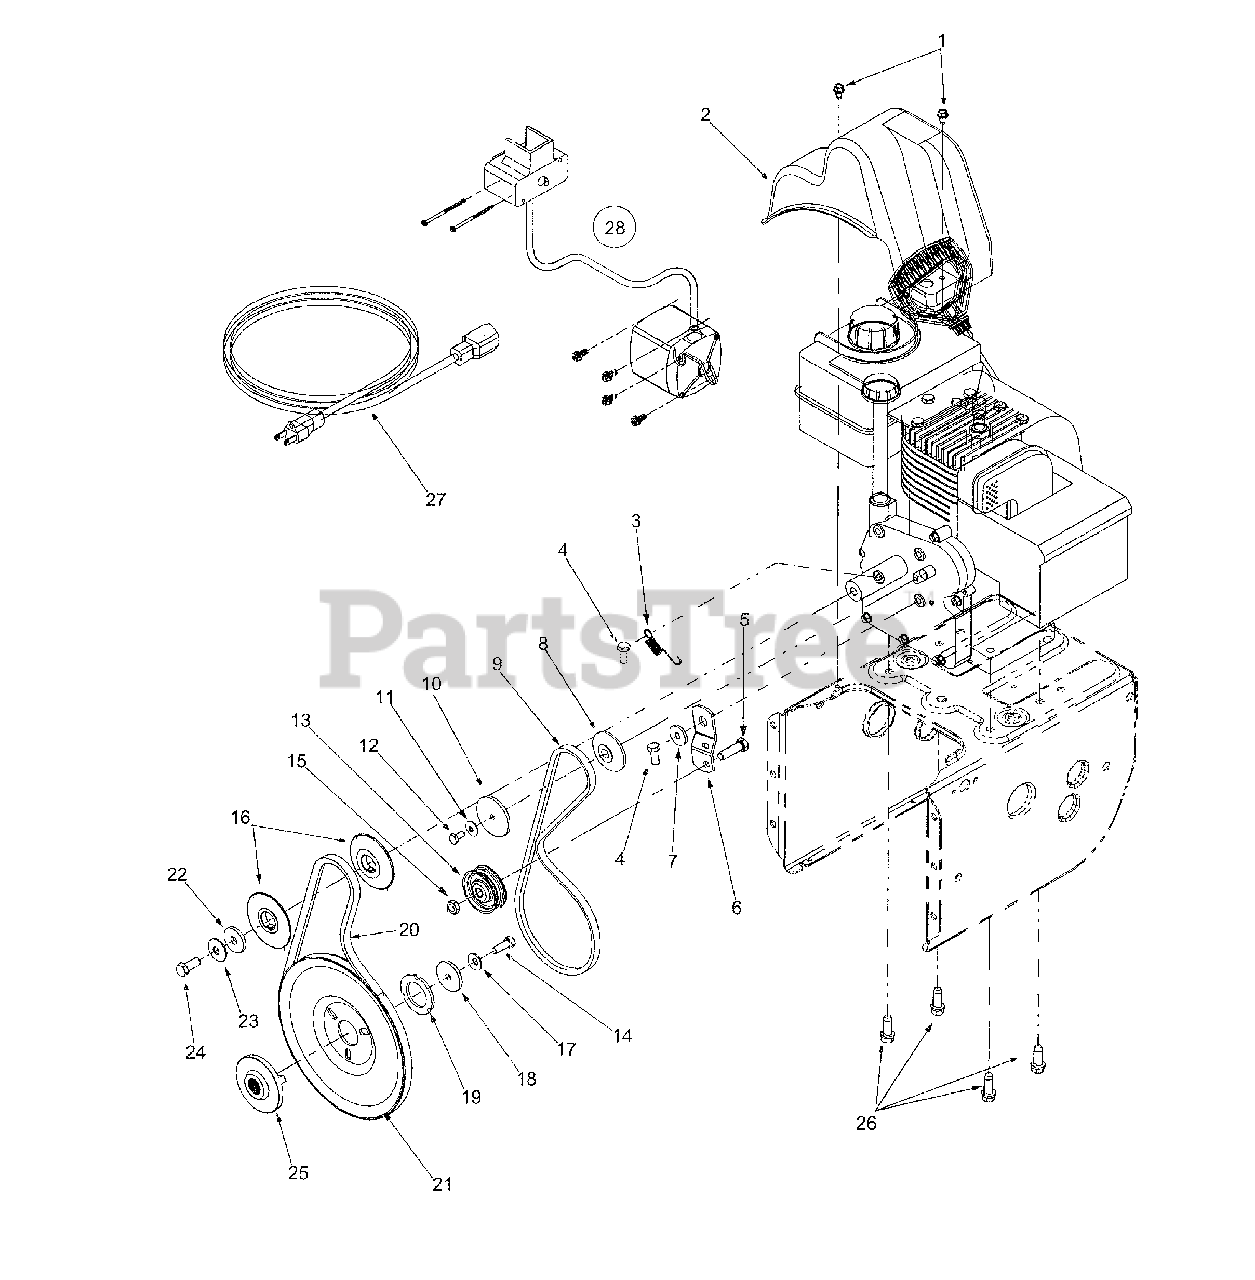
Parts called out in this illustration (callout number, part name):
1	Hex Washer Screw 1/4-20 x.625
2	Belt Cover
3	Extension Spring
4	Hex Screw 5/16-24 x .75
5	Hex Cap Screw 3/8-16 x 1.25
8	Pulley Half
9	V-Belt
10	Pulley Half
11	Bell Washer
12	Hex Cap Screw 1/4-28 x .50
13	Flat Idler
14	Lock Cap Screw 5/16-24
15	Lock Jam Nut 3/8-16
16	Pulley Half
17	Bell Washer
18	Flat Washer
19	Washer
20	Belt
21	Auger Pulley
22	Flat Washer
23	Bell Washer
24	Hex Cap Screw 3/8-24
25	Pulley
26	Hex Washer Screw 3/8-16 x 1.0
27	Extension Cord
28	Electric Start Kit
